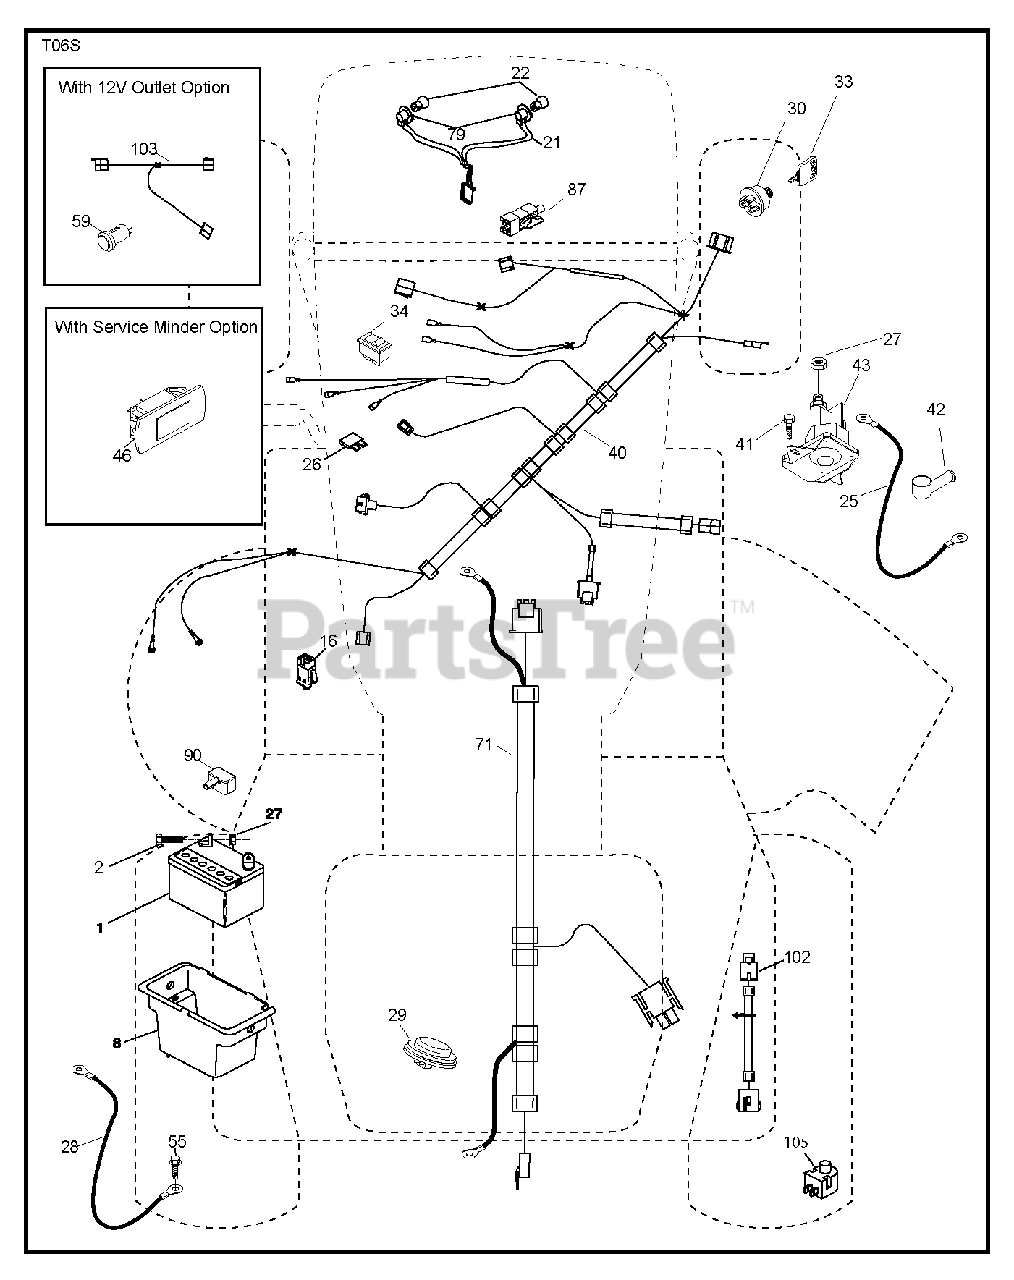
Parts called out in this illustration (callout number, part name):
1	REPL BY 532 12 38-99
2	BOLT.HEX.1/4.X.3/4.DICHROMATE
8	BOX.BATTERY.MNT.REAR.L
16	SWITCH INTERLOOK PUSH-IN
21	HARNESS ASSY LIGHT
22	LIGHTBULB
25	CABLE.STARTER.6GA.BL/RED.14.
26	FUSE 20AMP
27	NUT
28	CABLE.BLACK.18"REAR.BA
29	SWITCH.SEAT.DELTA.OPC.
30	SWITCH.IGN.DELTA.W.LGH.ROS
33	KEY.CHAIN.BLISTER.PACK.GEN.INT
34	SWITCH LT
40	HARNESS IGN. DASH
41	SCREW
42	TERMINAL COVER
43	SOLENOID.W/BRASS.PLUNGER
46	GUAGE.SRVCMNDR.HRMTR.
55	SCREW 5/16"
71	HARNESS.IGN.CHASS.TEX.REAR.BAT
79	BULB HOLDER ASM.
87	SWITCH.INTRLCK.CLUTCH.
90	COVER.TERMINAL.BATTERY
102	HARNESS PIGTAIL PCH TEX ROS
105	REVERSE SWITCH
